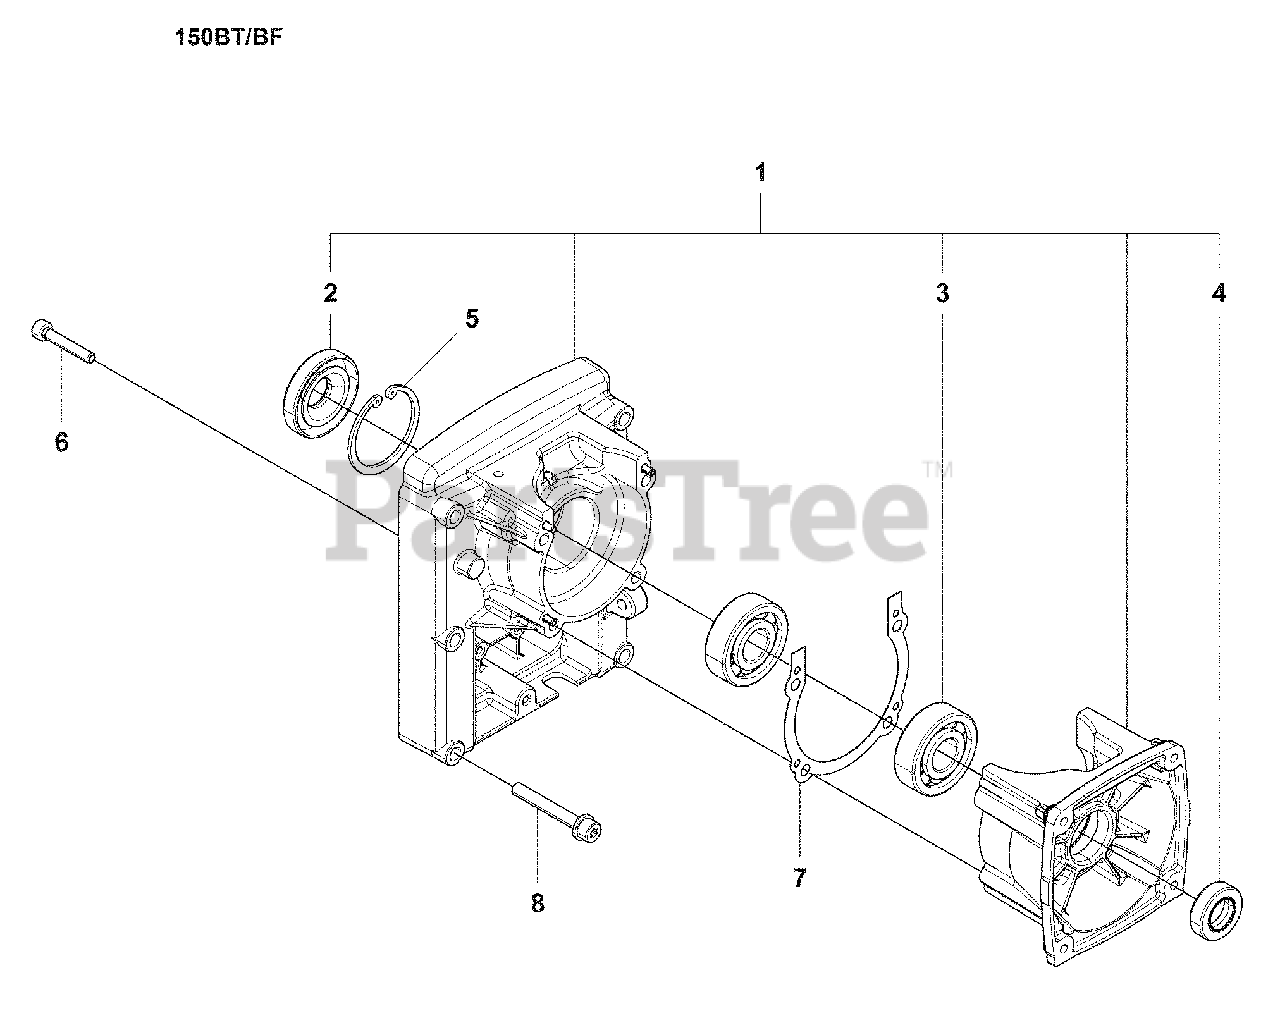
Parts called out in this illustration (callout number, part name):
3	Bearing
6	Bolt
8	Bolt
